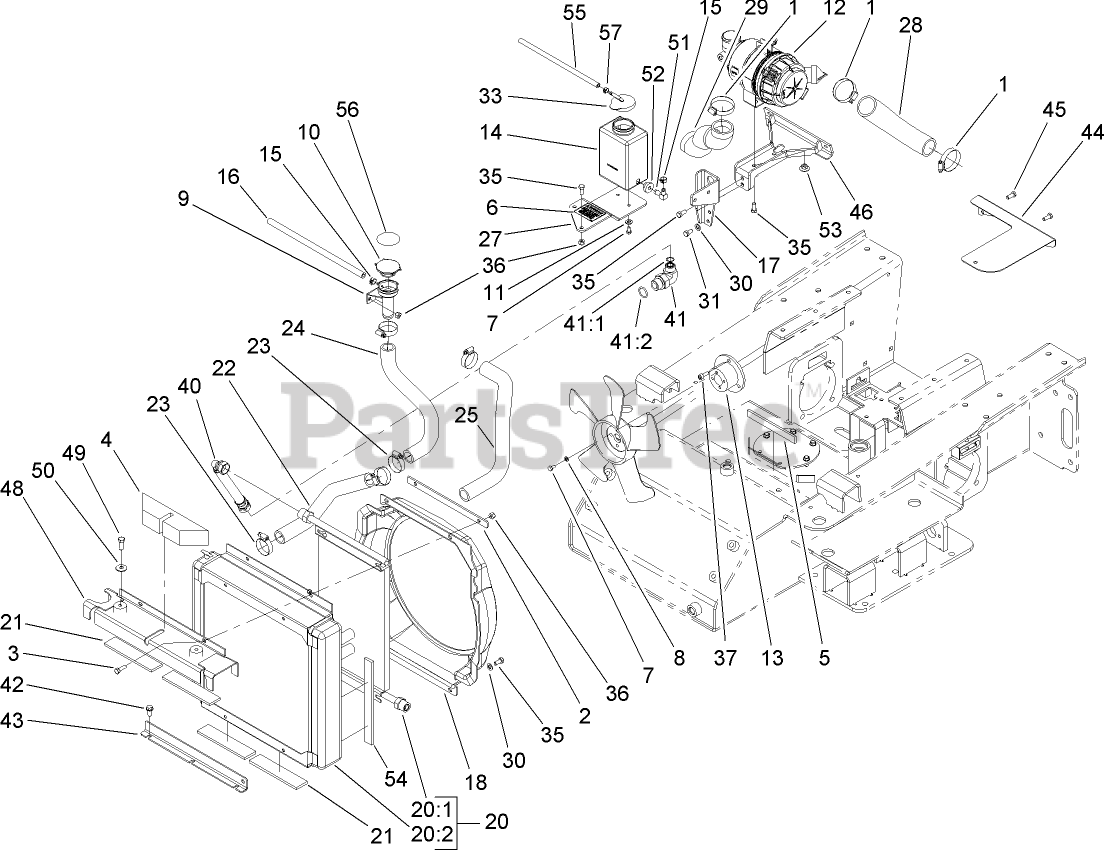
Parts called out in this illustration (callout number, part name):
1	CLAMP-HOSE
2	PLATE-BACKING
3	SCREW-HH
4	SEAL-FOAM
5	PAD-RUBBER
6	DECAL-ONLY, COOLANT
7	SCREW-HH
8	WASHER-LOCK
9	TUBE-FILLER, RADIATOR
10	CAP-RADIATOR
11	WASHER-FLAT
12	AIR CLEANER ASM
13	SPACER-FAN, MOUNT
14	TANK-OVERFLOW
15	CLAMP-HOSE
16	HOSE-LP
17	MOUNT-FILTER, AIR
18	SHROUD-FAN
20	RADIATOR AND OIL COOLER ASM
20:1	COOLER-OIL, HYD
20:2	RADIATOR
21	PAD-RUBBER
22	HOSE-RADIATOR
23	CLAMP-HOSE
24	HOSE-RADIATOR
25	HOSE-RADIATOR
27	BRACKET-TANK, OVERFLOW
28	HOSE-AIR, INLET
29	HOSE-AIR
30	WASHER-PLAIN
31	BOLT
33	CAP-TANK, OVERFLOW
35	SCREW-HH
36	NUT-LOCK, NI
37	SCREW-CAP, HSH
40	HYD HOSE ASM
41	FITTING-ELBOW 90
41:1	O-RING
41:2	O-RING
42	SCREW-HWHTF
43	MOUNT-RADIATOR
44	PLATE-BAFFLE, STARTER
45	SCREW-HH
46	BRACKET ASM
48	BRACKET-RADIATOR
49	SCREW-HH
50	WASHER-SPRING
51	FITTING-ELBOW
52	BUSHING-VALVE, FUEL
53	NUT-HF
54	FOAM-SEAL
55	HOSE-LP
56	DECAL-CAP, RADIATOR
57	CLAMP-HOSE
